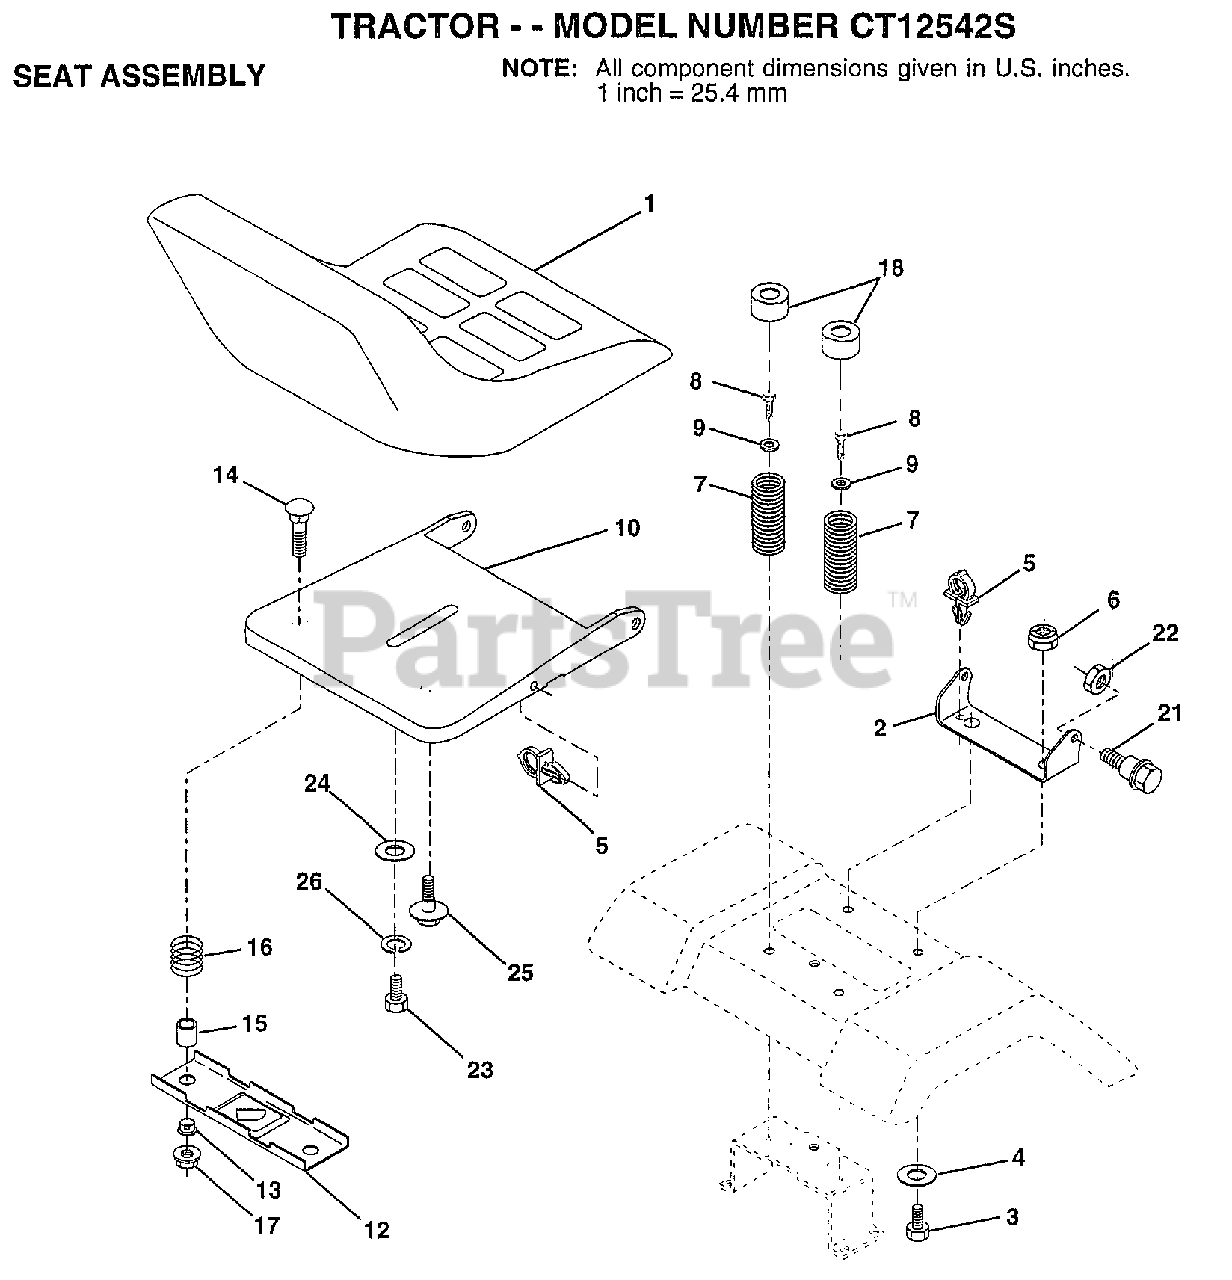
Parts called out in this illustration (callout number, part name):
2	BRACKET PVT SEAT
3	BOLT
4	WASHER PM
5	CLIP.PUSH-IN.HING
6	NUT
7	SPRING COMPRESSIO
8	SCREW GTV
9	WASHER
10	PAN-SEAT
12	BRKT SWITCH
13	BUSHING
14	BOLT-RD HD SQ NK
15	SPLIT SPACER
16	SPRING
21	"BOLT,SHOULDER"
22	NUT
23	BOLT
24	WASHER
25	"BOLT,SHOULDER"
26	LOCKWASHER
